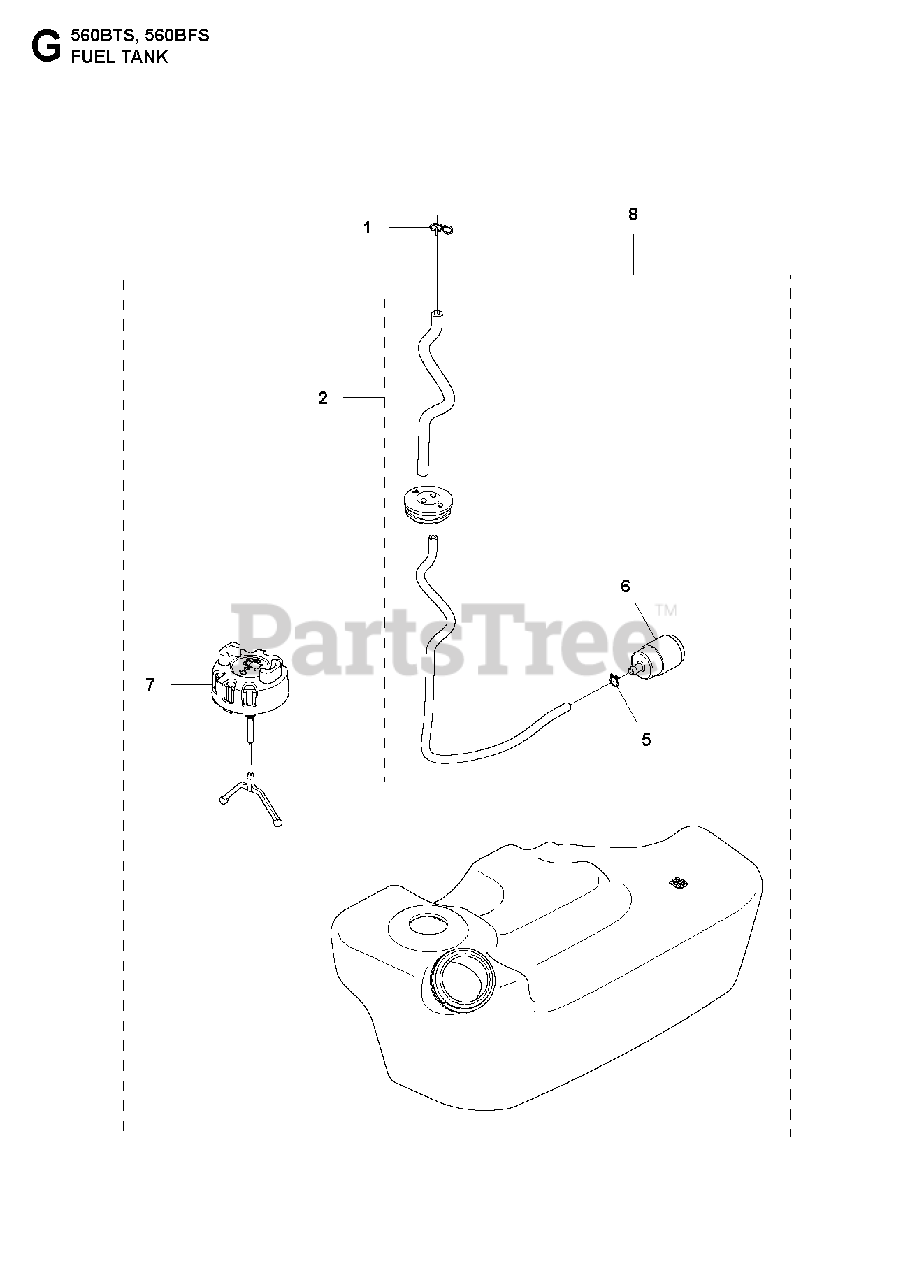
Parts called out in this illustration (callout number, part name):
2	PIPE
5	CLIP
6	FILTER ASSY
7	FUEL CAP ASSY
8	FUEL TANK ASSY
